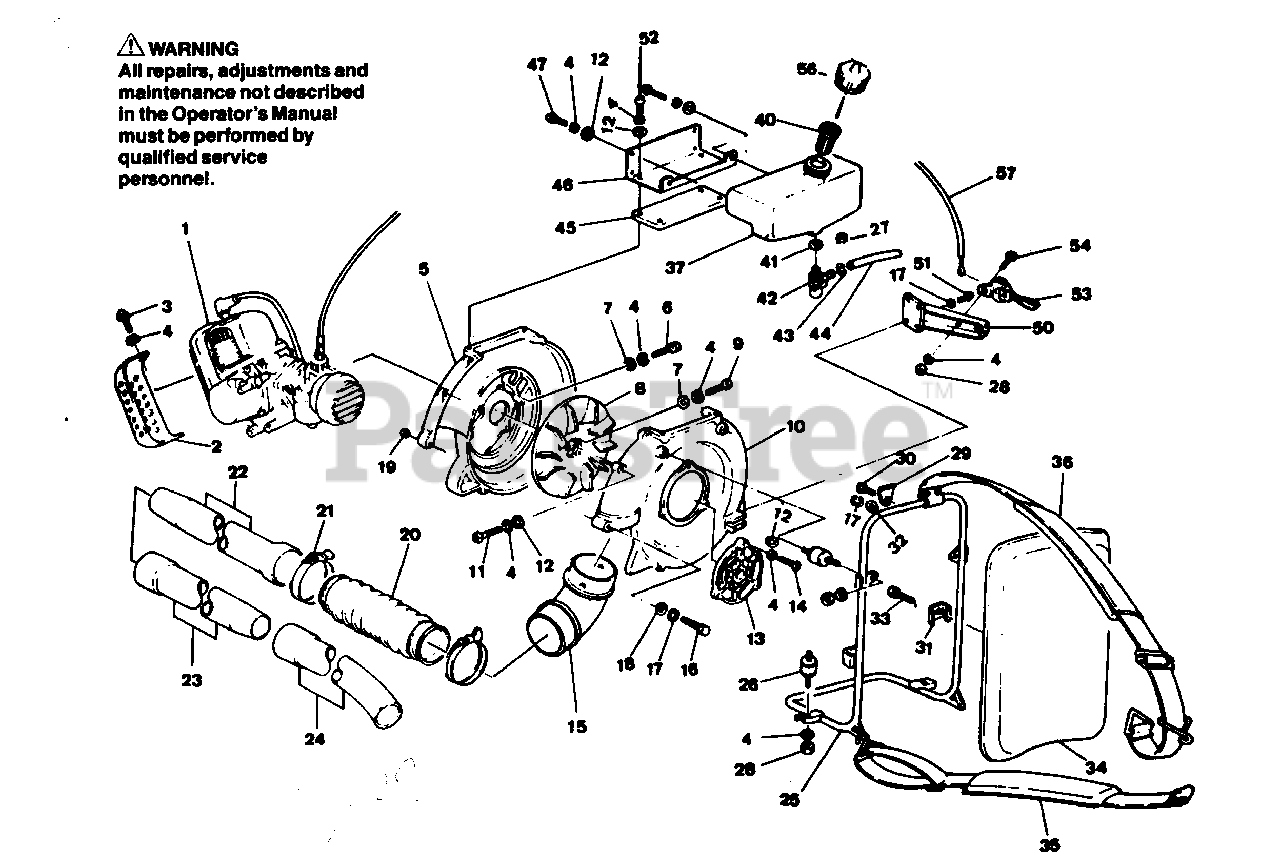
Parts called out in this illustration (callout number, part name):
1	Model KT28 Engine
2	Muffler Cover
4	Lock Washer
5	Fan Case (Rear)
10	Fan Case (Front)
15	Spray Bent Pipe
17	Lock Washer
20	Flexible Pipe
21	Wire Clamp
22	Base Pipe
23	Duster Middle Pipe
24	Duster Base Pipe
25	Knapsack Frame
26	Isolator
27	Washer Based Nut
29	Back Plate Fitting (A)
31	Back Plate Fitting (B)
34	Back Plate
35	Knapsack Belt (Right)
36	Knapsack Belt (Left)
37	Fuel Tank
40	Strainer
41	Seal Washer
42	Fuel Cock
43	Clamp Ring
44	Vinyl Pipe
45	Isolator
50	Supporter, Graduation Plate
53	Throttle Lever
56	Fuel Cap Assembly
57	Throttle Cable
